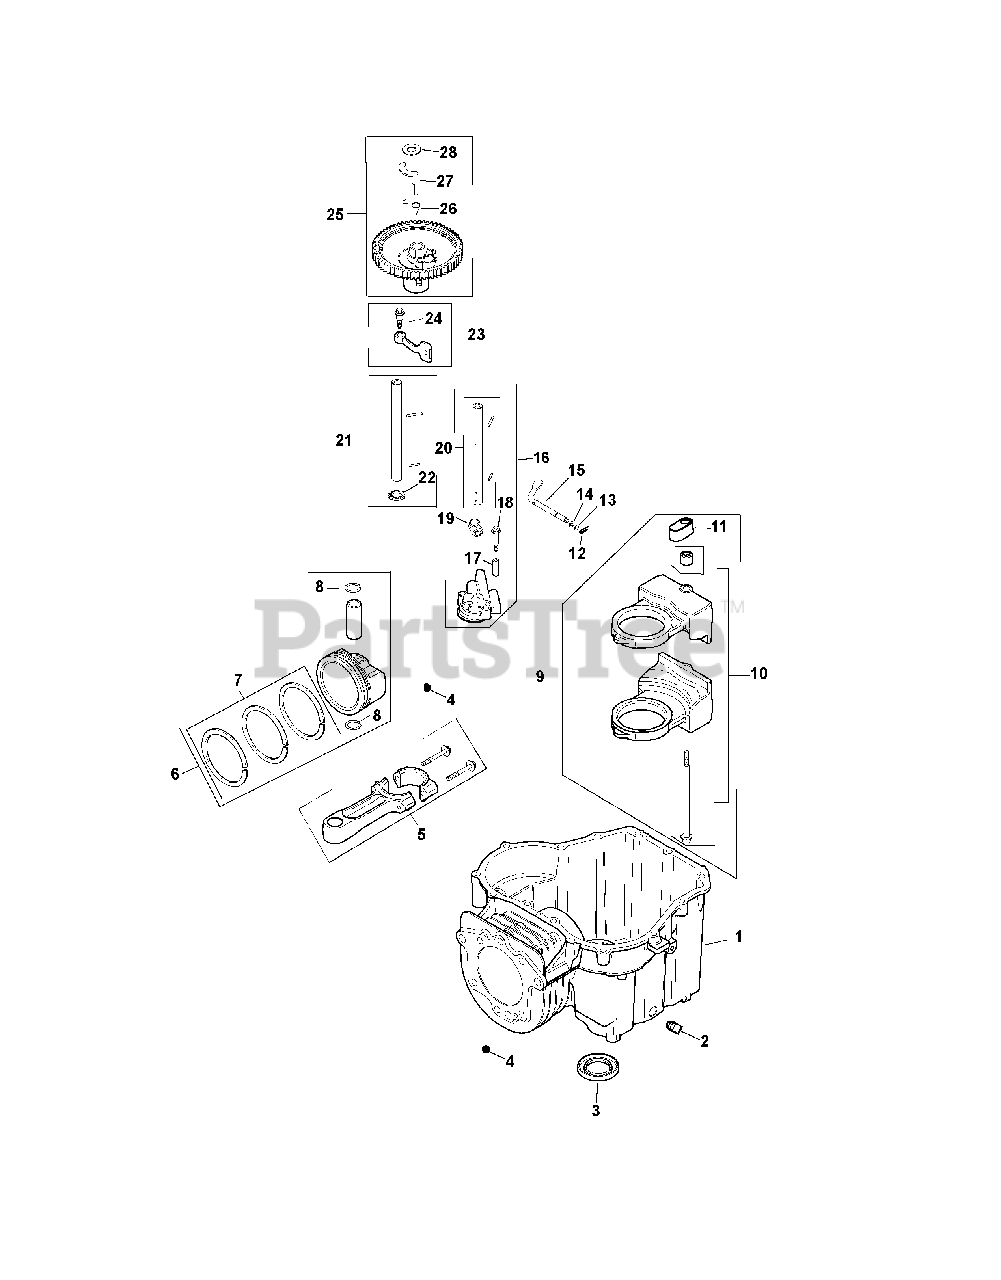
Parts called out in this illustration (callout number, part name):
2	Pipe Plug Sq. hd. 3/8"
3	Oil Seal
4	Check Valve Ball
5	Connecting Rod (Std.)
6	Piston w/Ring Set (Std.)
7	Ring Set (94 mm) (AS REQUIRED)
8	Piston Pin Retainer
9	Balance Weight Kit
10	Screw/Guide Pin Kit
12	Hitch Pin Clip
14	Plain Washer
15	Governor Cross Shaft
16	Oil Pump Assembly (17-20)
17	Oil Pump Screw Spacer
18	Oil Pump Screw
19	Oil Pump Outlet Seal
20	Intake Cam Center Shaft
21	Exhaust Cam Center Shaft
22	Thrust Washer
23	Cam Lever Assembly (24)
24	Shoulder Screw
25	Cam Gear Assembly (26-28)
27	ACR Weight
28	ACR Thrust Washer
